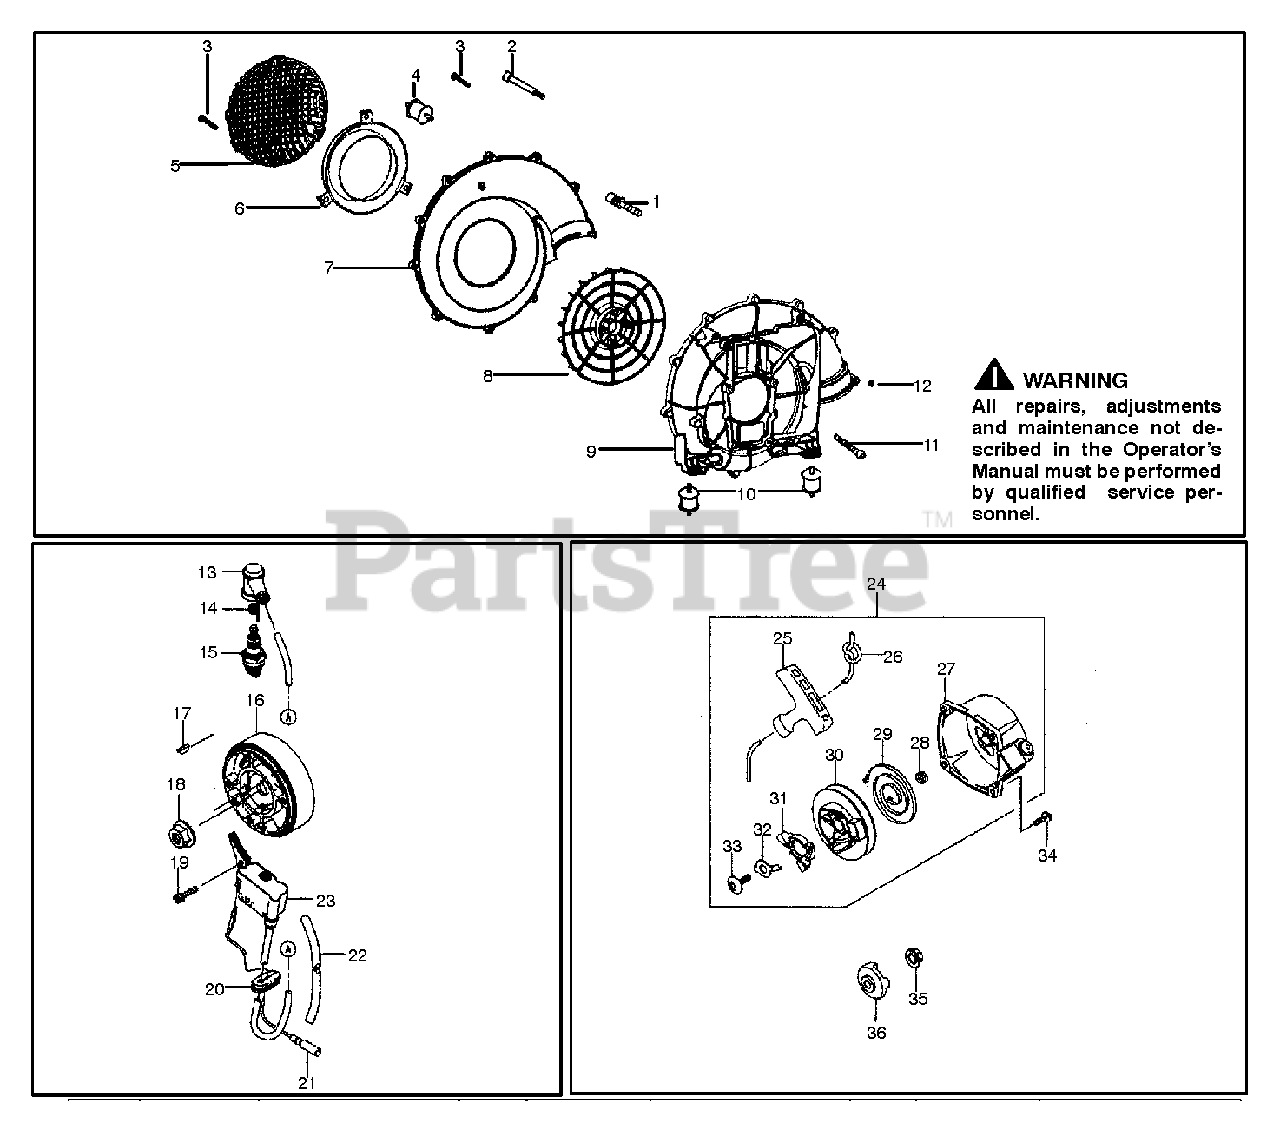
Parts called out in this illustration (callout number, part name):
1	SOCKET SCREW SUS W/SW M5
2	SOCKET SCREW M5 X 65
3	TAPPING SCREW 5 X 20
4	VIBRO ISOLATING RUBBER
5	FAN COVER
7	FAN CASE
9	FAN CASE
10	VIBRO ISOLATING RUBBER
11	SOCKET SCREW M6 X 30
12	NYLON NUT
15	PLUG SPARK
16	FLYWHEEL
17	KEY WOODRUFF
19	BOLT 4 X 20
21	WIRE LEAD
22	TUBE KAAZ
23	COIL ASSY IGNITION
24	STARTER RECOIL
25	GRIP STARTER RECOIL
26	ROPE 3.5 X 1000
27	CASE STARTER RECOIL
29	SPRING RECOIL
30	REEL STARTER RECOIL
31	PAWL STARTER RECOIL
32	RETAINER
34	SCREW 4 X 16
36	PULLEY STARTING
